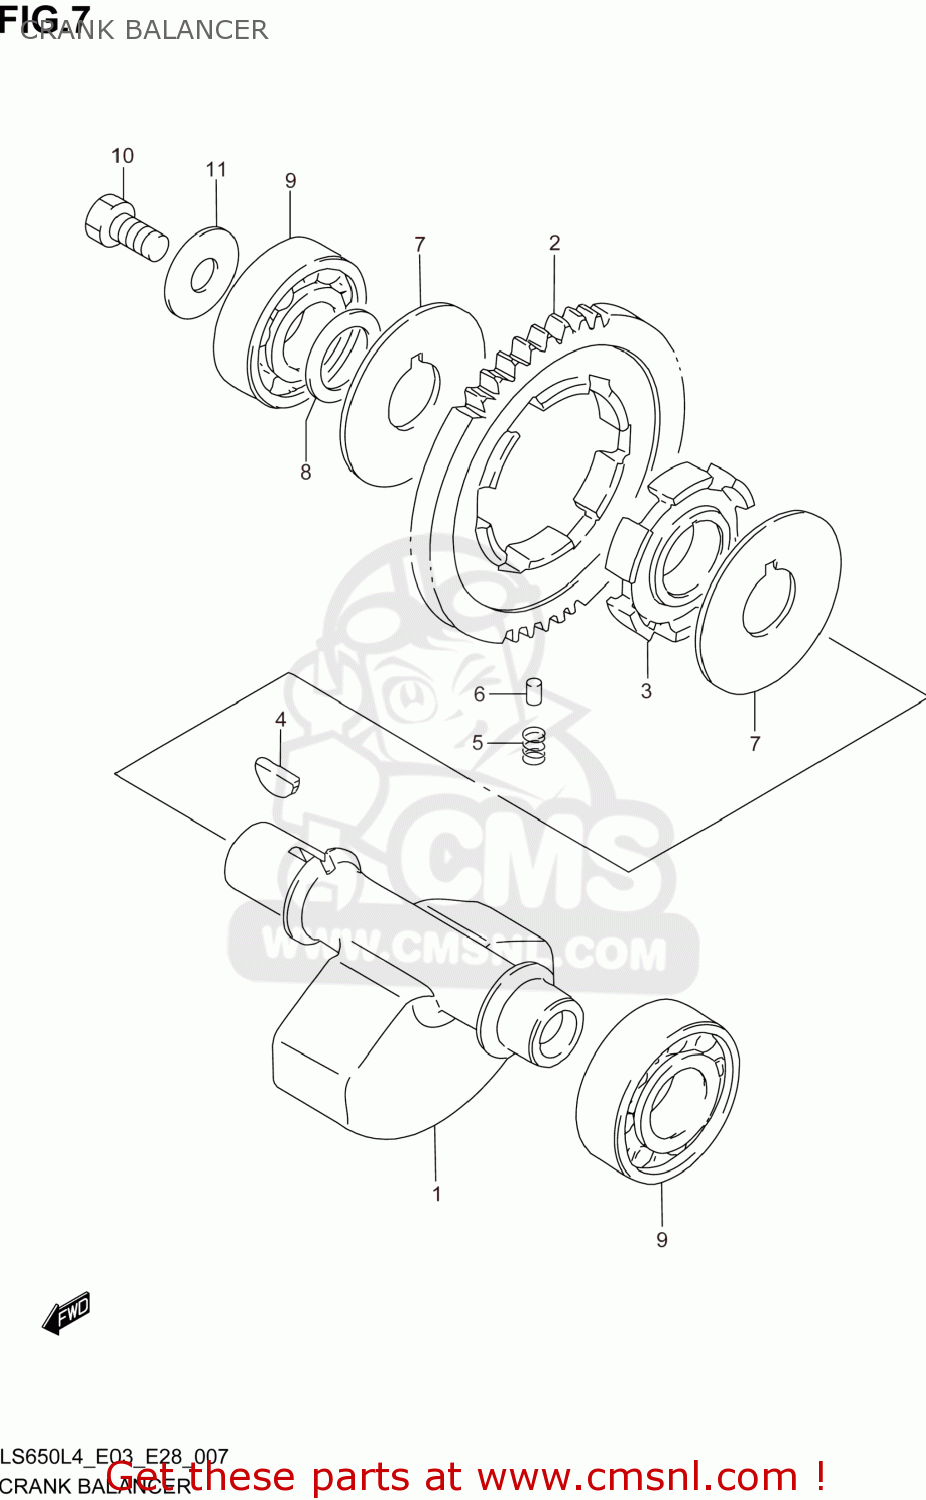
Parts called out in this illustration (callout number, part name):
1	SHAFT,CRANK BALANCER
2	GEAR,CRANK BALANCER DRIVEN
3	RACE,CRK BAL DRIVEN GEAR INNER
4	KEY
5	SPRING
6	PIN(4.5X9.5)
7	WASHER
8	SHIM(20X28X0.5)
9	BEARING(20X47X14)
10	BOLT
11	WASHER
